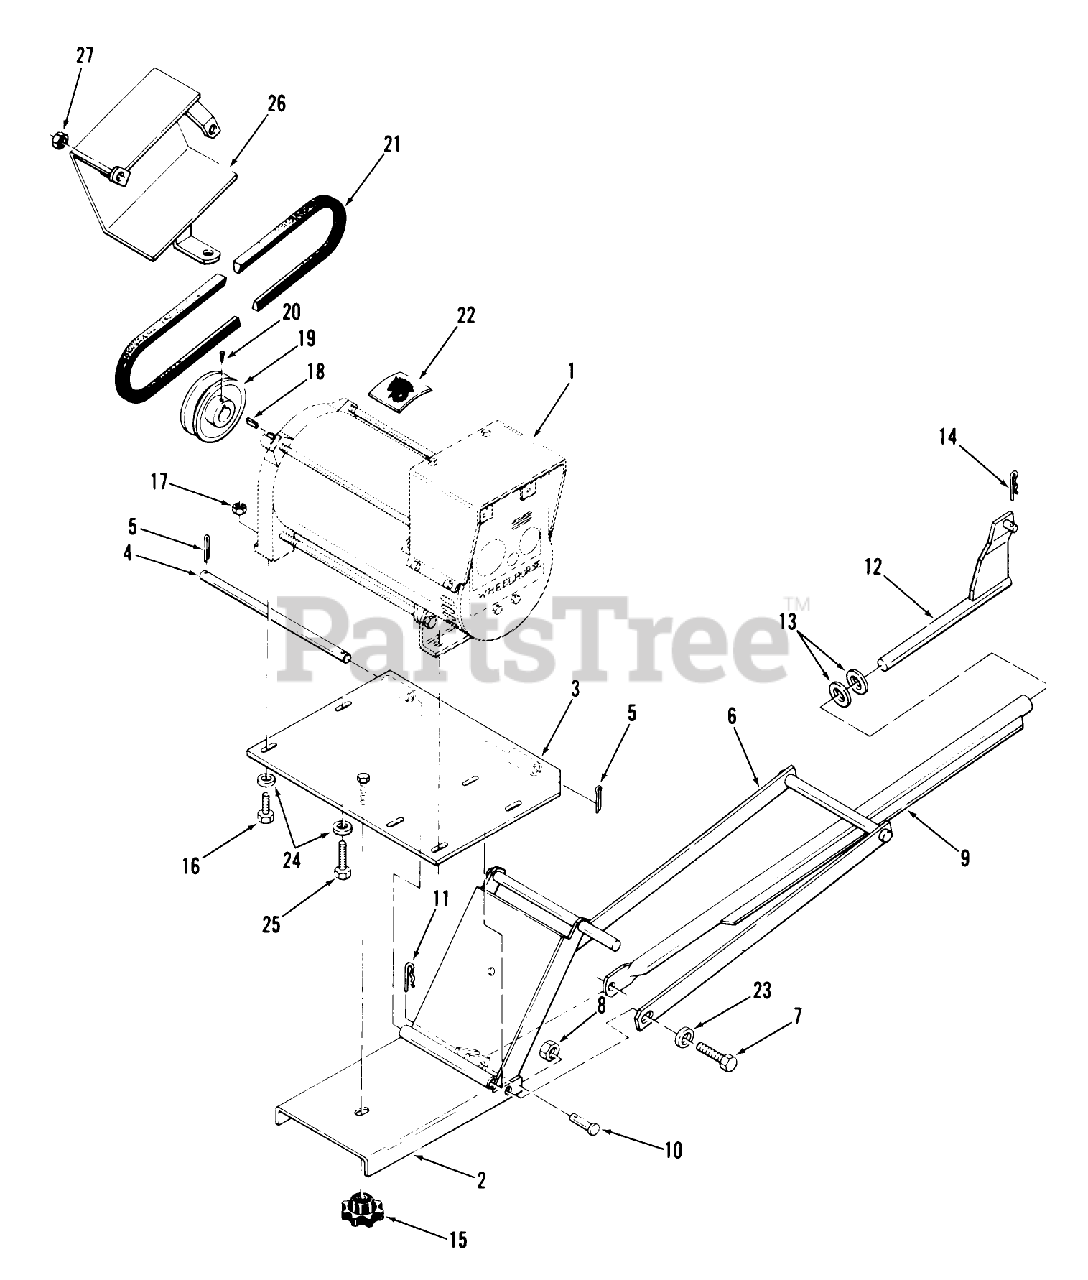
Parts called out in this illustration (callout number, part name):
1	ORDER GENERAC 8212R
1	ORDER GENERAC 8212
11	Hairpin Cotter
14	Hairpin
22	DECAL-LOGO
24	WASHER 5/16 SAE
